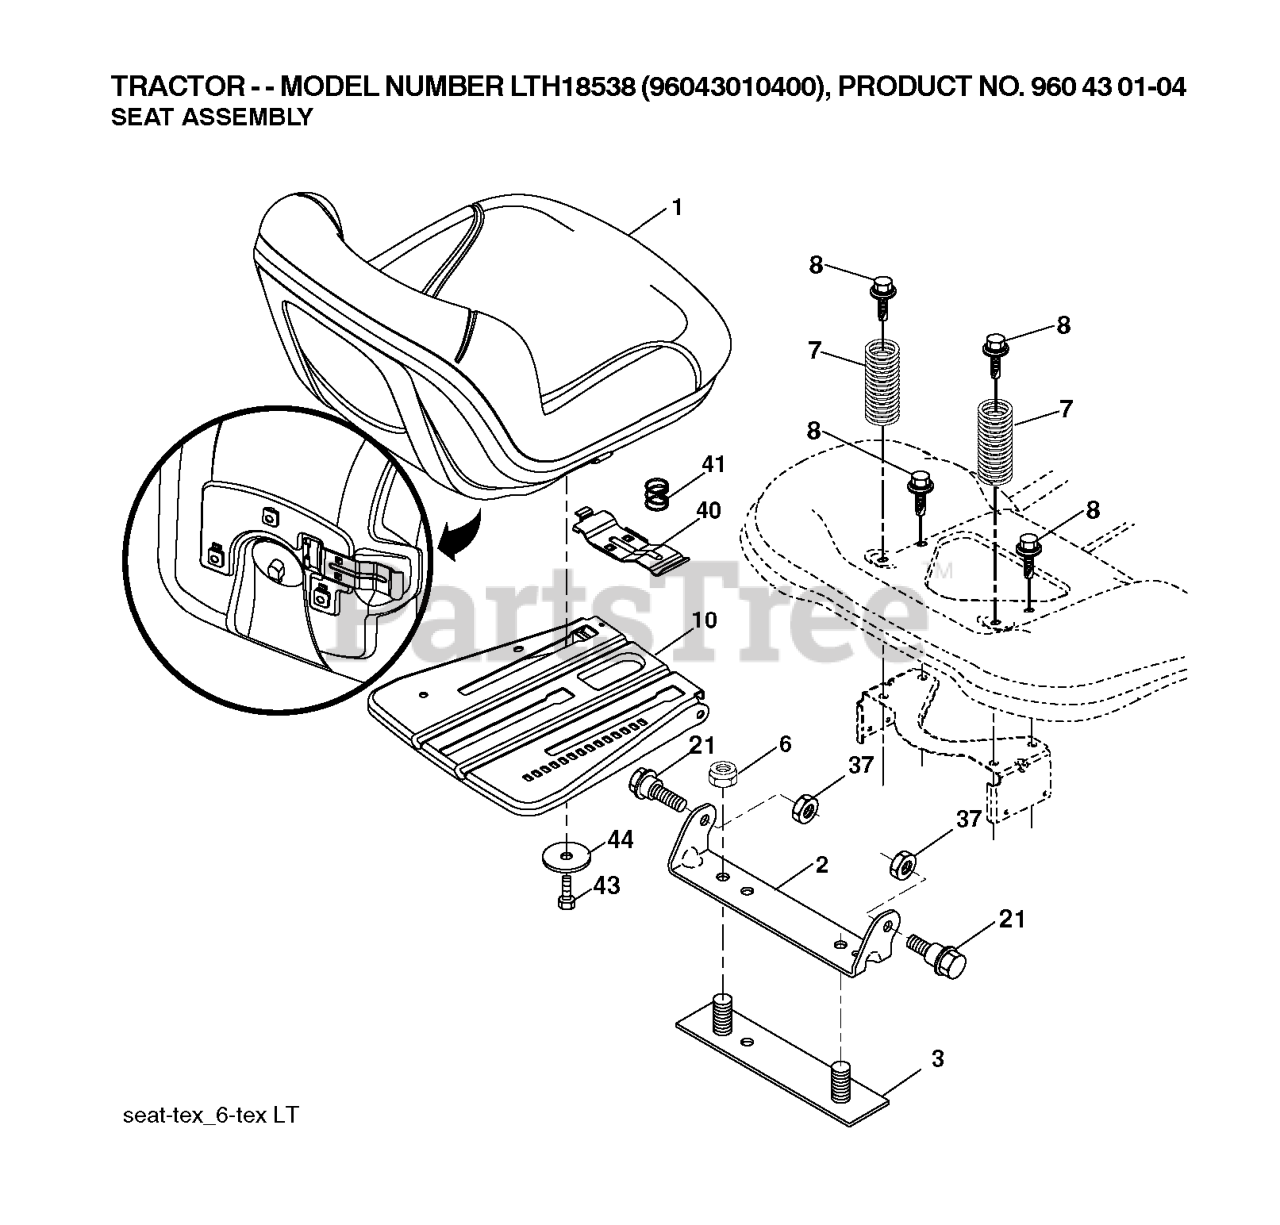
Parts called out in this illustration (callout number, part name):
1	RP SEAT.TH130.GRY.MILSCO.
2	BRKT.PIVOT.FENDER
3	STRAP
6	NUT
7	SPRING COMPRESSION
8	BOLT.5/16-18UNCX3/4 W/SEMS.BLK
10	PAN.ASM.SEAT.3PT
21	BOLT.SHOULDER.5/16-18
37	NUT.71038.31-18.HEX.NYLOCK
40	HANDLE.SLIDE.SEAT.TEX.BLACK
41	SPRING.LATCH.SEAT.TEX
44	WASHER 13/32 X 2-3/8 X 12GA
